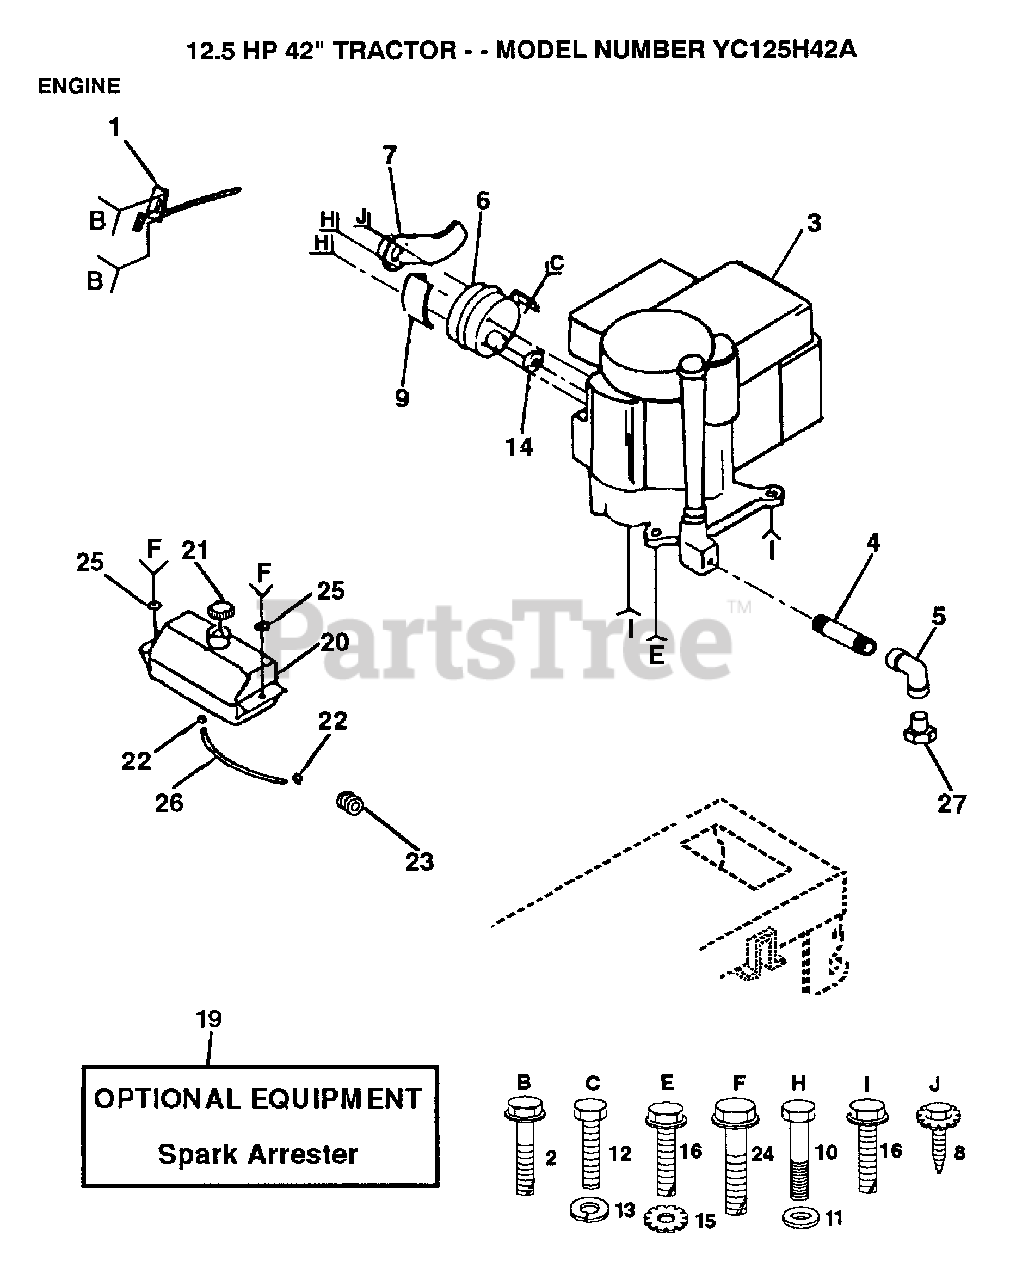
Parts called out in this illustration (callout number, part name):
1	THROTTLE CONTROL
2	SCREW LT
4	PIPE NIPPLE
5	ELBOW
6	MUFFLER LTV
7	DEFLECTOR MUFFLER
9	SHIELD HEAT LTV
10	"BOLT,HEX"
11	WASHER T
12	BOLT
13	LOCKWASHER
15	LOCKWASHER
16	SCREW
20	TANK.FUEL.LT.
22	HOSE CLAMP
24	SCREW HEX CRT
25	WASHER
26	FUEL LINE T
